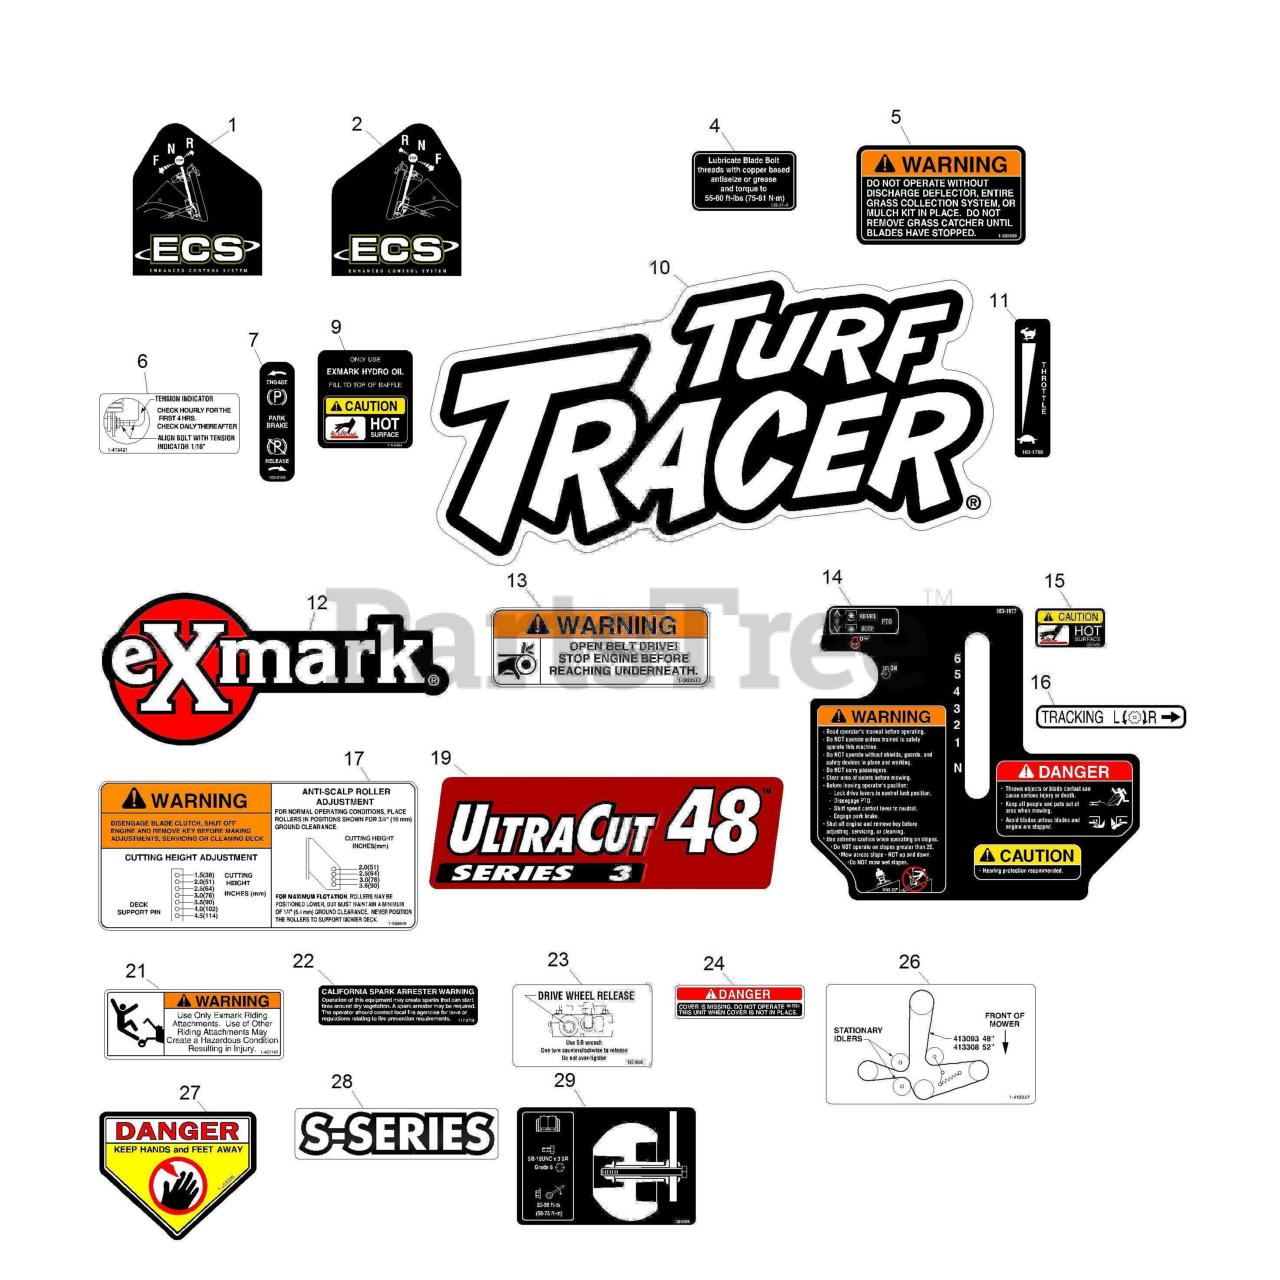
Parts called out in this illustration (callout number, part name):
1	DECAL,LH ECS INSTRUCTION
2	DECAL,RH ECS INSTRUCTION
4	DECAL,BOLT TORQUE
5	DECAL-WARNING, DISCHARGE
6	DECAL,INDICATOR
7	DECAL-BRAKE, PARK
9	DECAL-HYDRAULIC TANK
10	DECAL,TTH MODEL
11	DECAL,THROTTLE ONLY
12	DECAL,EXMARK LOGO
13	DECAL,BELT DRIVE
14	DECAL,ECS CONSOLE
15	DECAL-CAUTION
16	DECAL,TRACKING ADJUST
17	DECAL,ANTI SCALP
19	DECAL-ULTRACUT 48 SERIES
21	DECAL,SULKY WARNING
22	DECAL-ARRESTER, SPARK
23	DECAL,DRIVE RELEASE
24	DECAL-COVER, MISSING
26	DECAL,BELT ROUTING
27	DECAL-DANGER
28	DECAL-S-SERIES
29	DECAL-ROLLER MOUNTING
